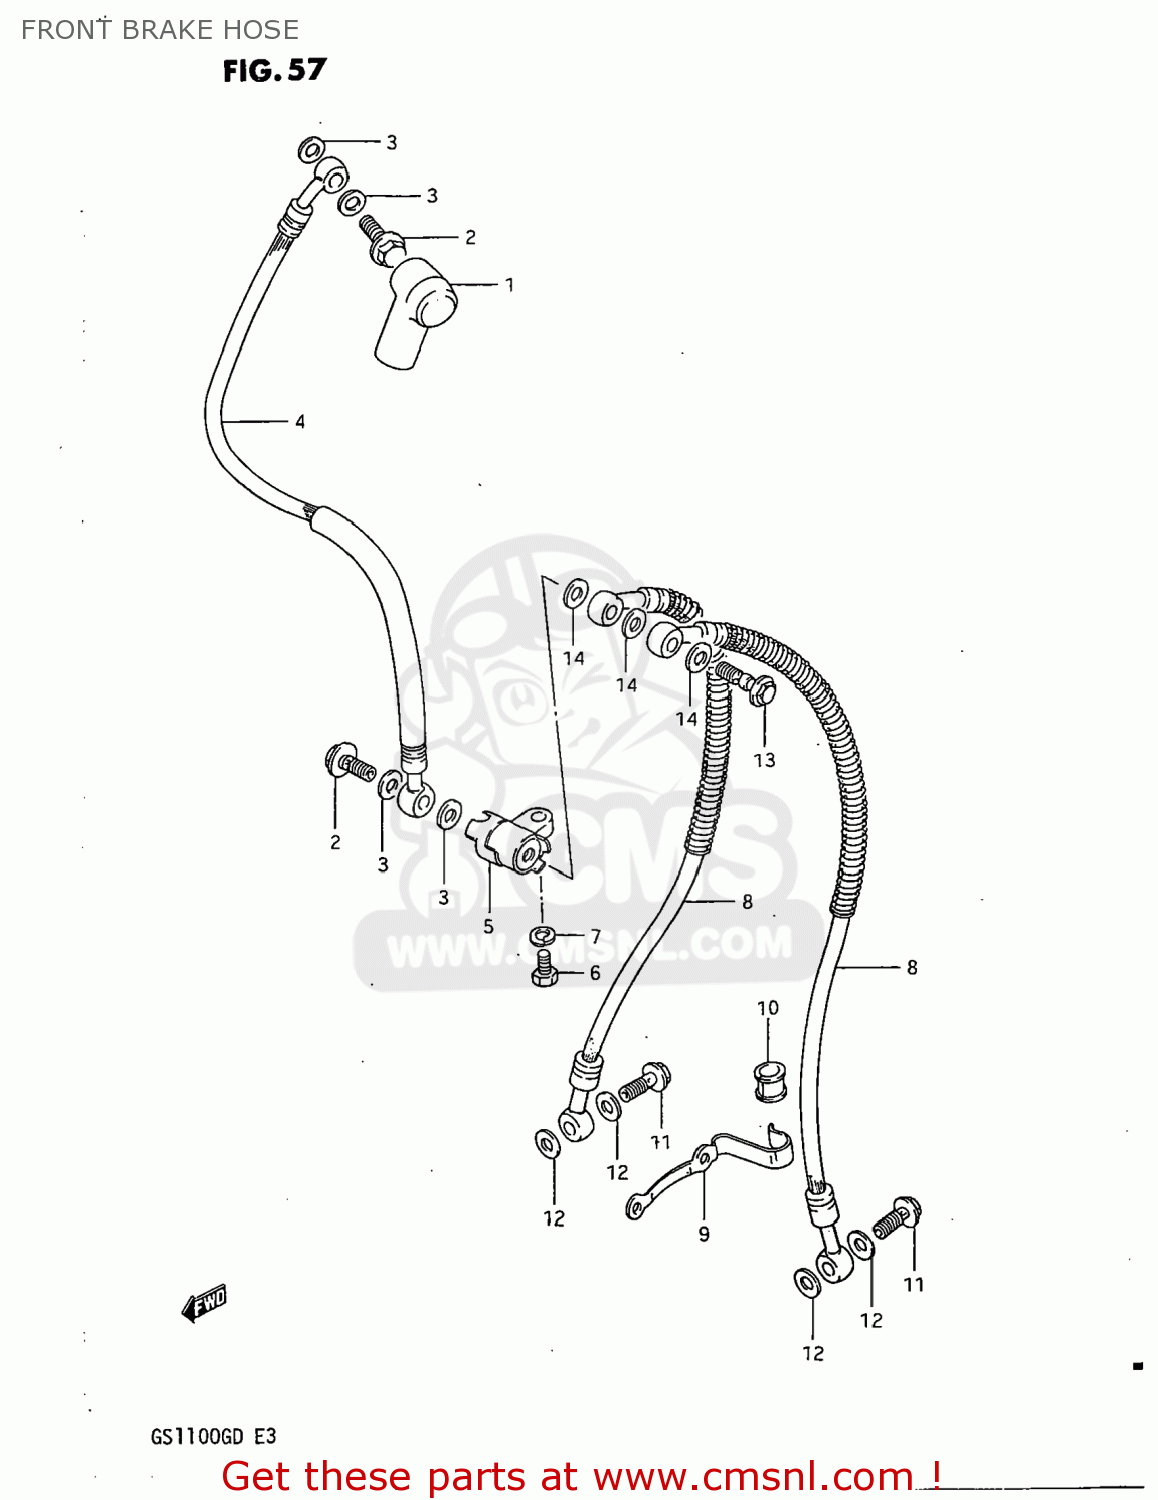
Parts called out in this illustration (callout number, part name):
1	BOOT,MASTER CYLINDER
2	BOLT,UNION
3	WASHER
4	HOSE,BRAKE NO.1
5	JOINT,BRAKE HOSE
6	BOLT
7	LOCK WASHER
8	HOSE,FRONT BRAKE
9	GUIDE,BRAKE HOSE NO.2
10	BUSH,BRAKE HOSE GUIDE,NO.2
11	BOLT,UNION
12	WASHER
13	BOLT,UNION
14	WASHER
